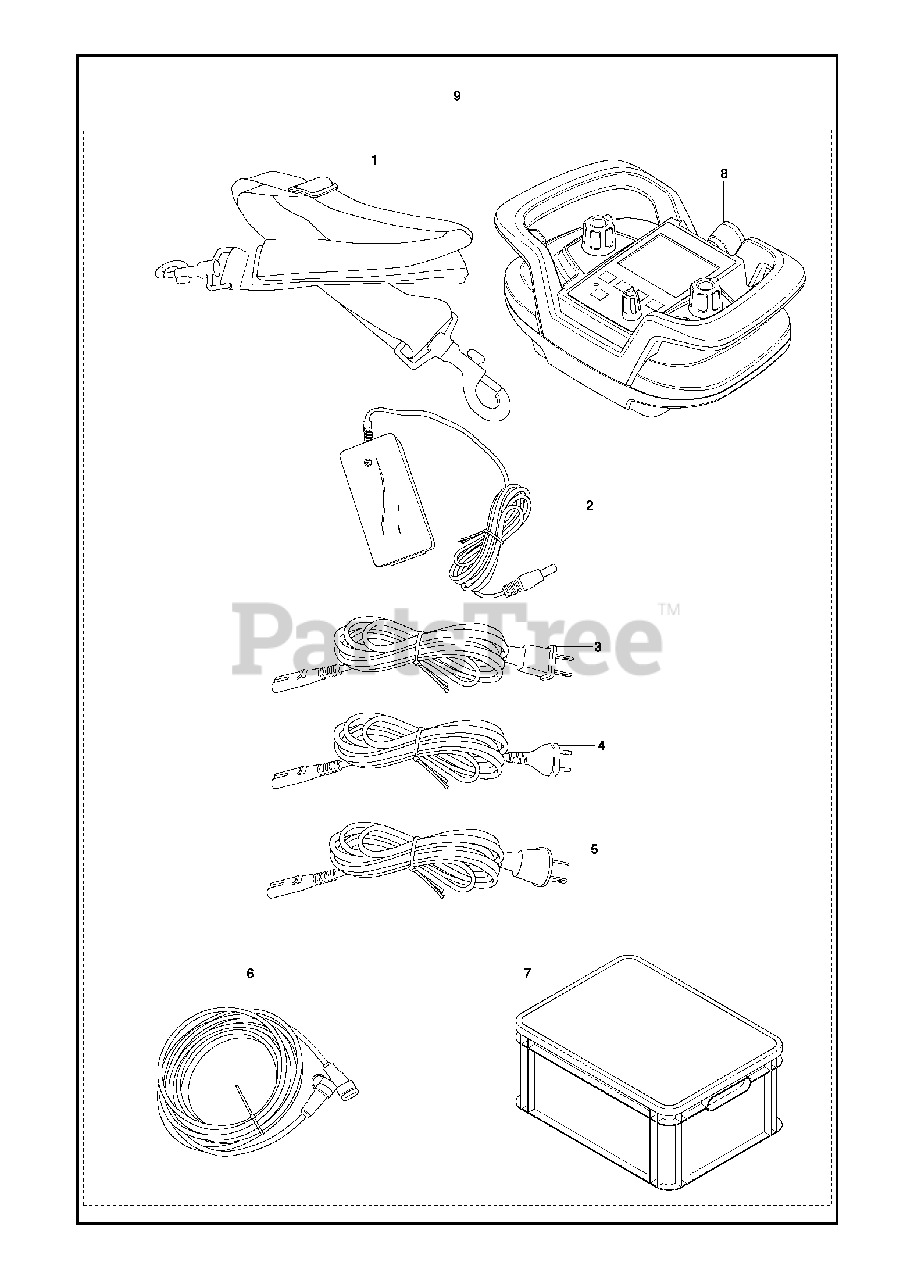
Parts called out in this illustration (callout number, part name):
1	SHOULDER STRAP
7	BOXOrange box from serial number 20143700001
9	CONTROL UNITOrange box from serial number 20143700001
